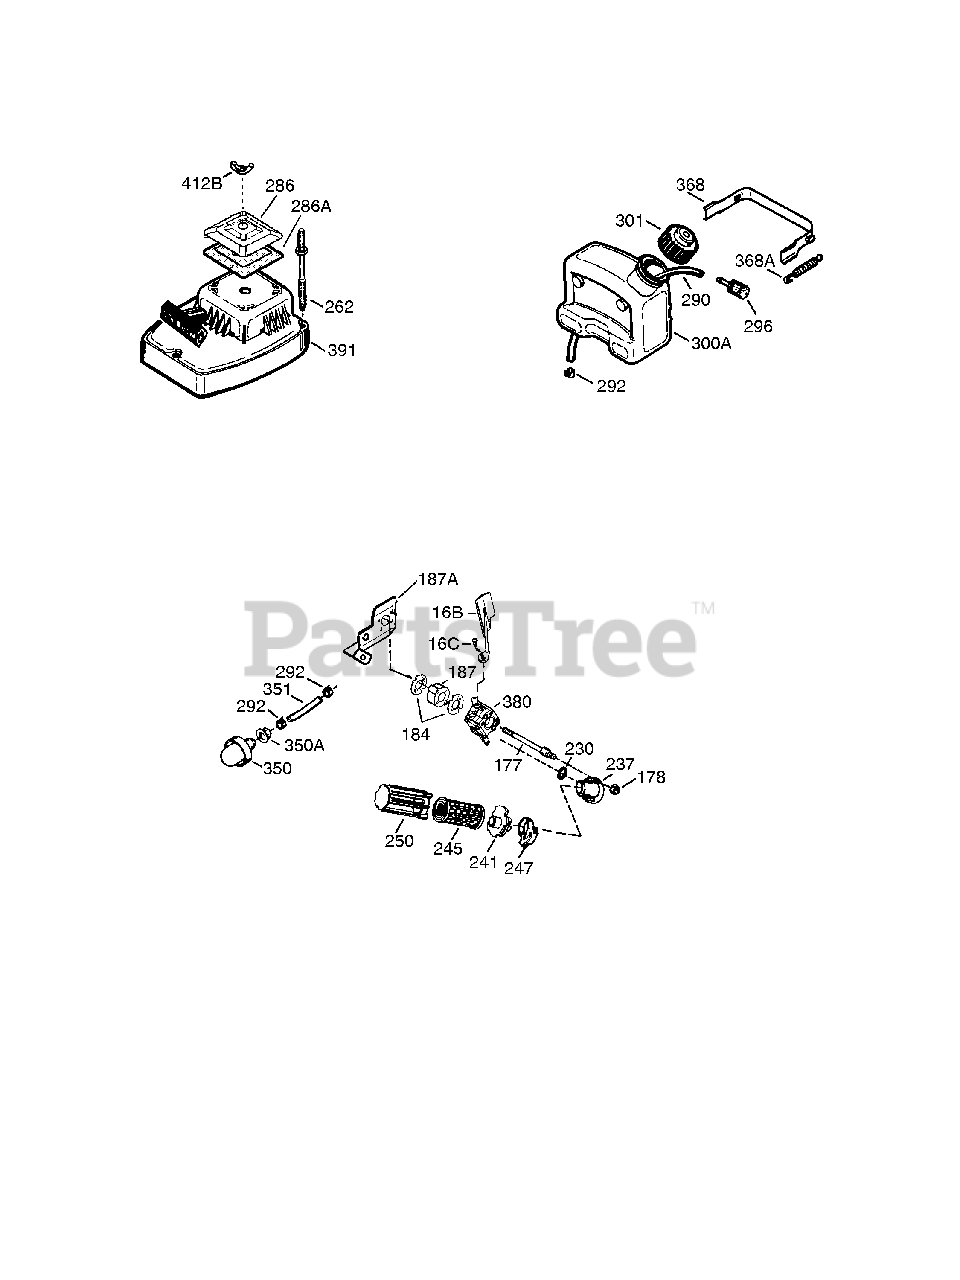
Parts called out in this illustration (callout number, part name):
16B	Air Vane
16C	Screw, T-8, 3-48 x 7/32"
177	Carburetor Mounting Stud
178	Lock Nut, 10-24
184	Carburetor Gasket
187A	Air Baffle (Incl. 184 & 187)
230	"O" Ring
245	Air Filter (Poly) (also available in Packaged Part #740097 (incl. 450255 & 450257))
250	Air Cleaner Cover
290	Fuel Line
292	Fuel Line Clamp
301	Fuel Cap
380	Carburetor (Incl. 184)
391	Recoil Starter & Housing Ass'y.
520	Clutch (Supplied by OEM)
900	Replacement engine 710580, order from 71-999
900	Replacement S/B 710542B, order from 7 1-999
